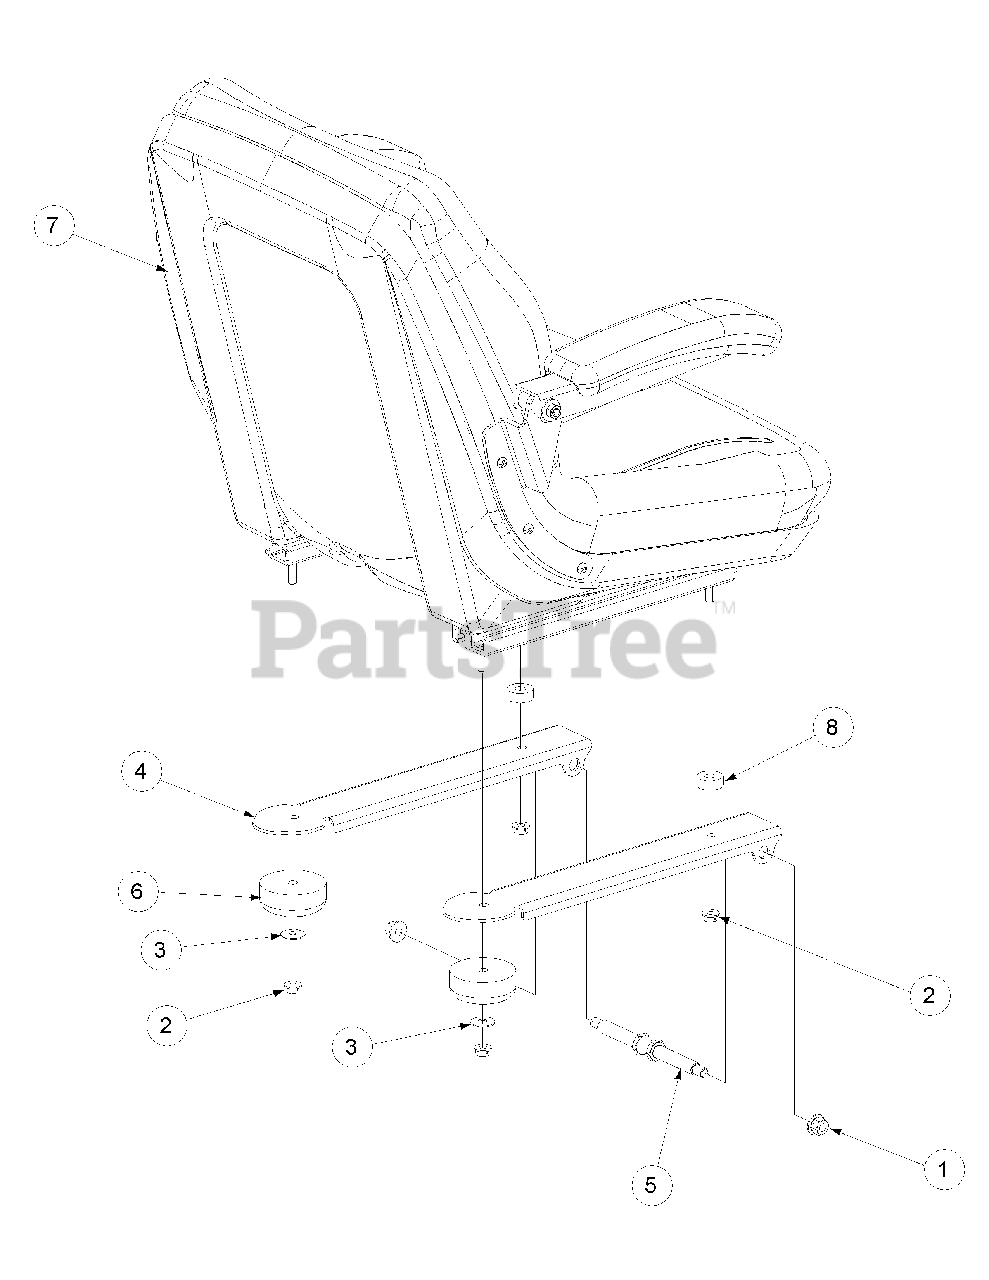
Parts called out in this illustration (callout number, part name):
1	Nut, Hex 3/8-16 Flange Lock
2	Lock Nut, Hex Flange, 5/16-18
3	Flat Washer, .406 ID, 1.00 OD, .105
4	Mounting Bracket, Seat
5	Shoulder Screw, .50x2.345, 3/8-16
6	Grommet, 2.5 OD x 1.0 Long
7	Adjustable Seat, Black
8	Spacer, .406 ID x 1.00 OD x .38
